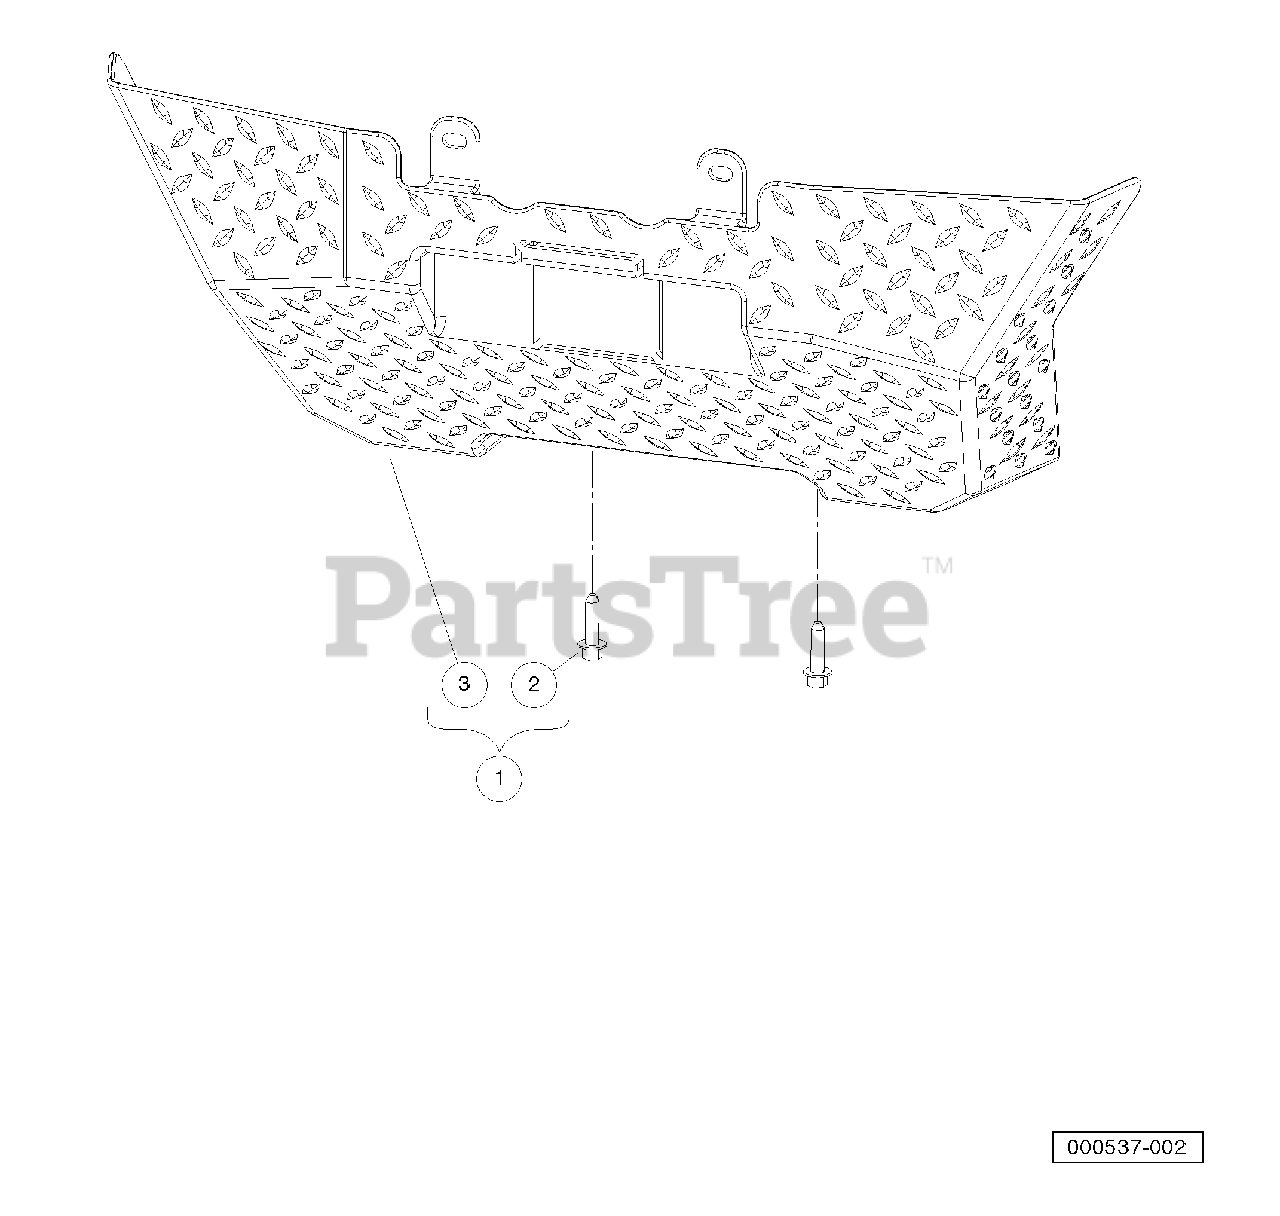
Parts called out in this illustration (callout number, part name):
1	Instl, Skid, Std
2	Screw, M8X125X30, Hex
3	Plate, Skid, Std
